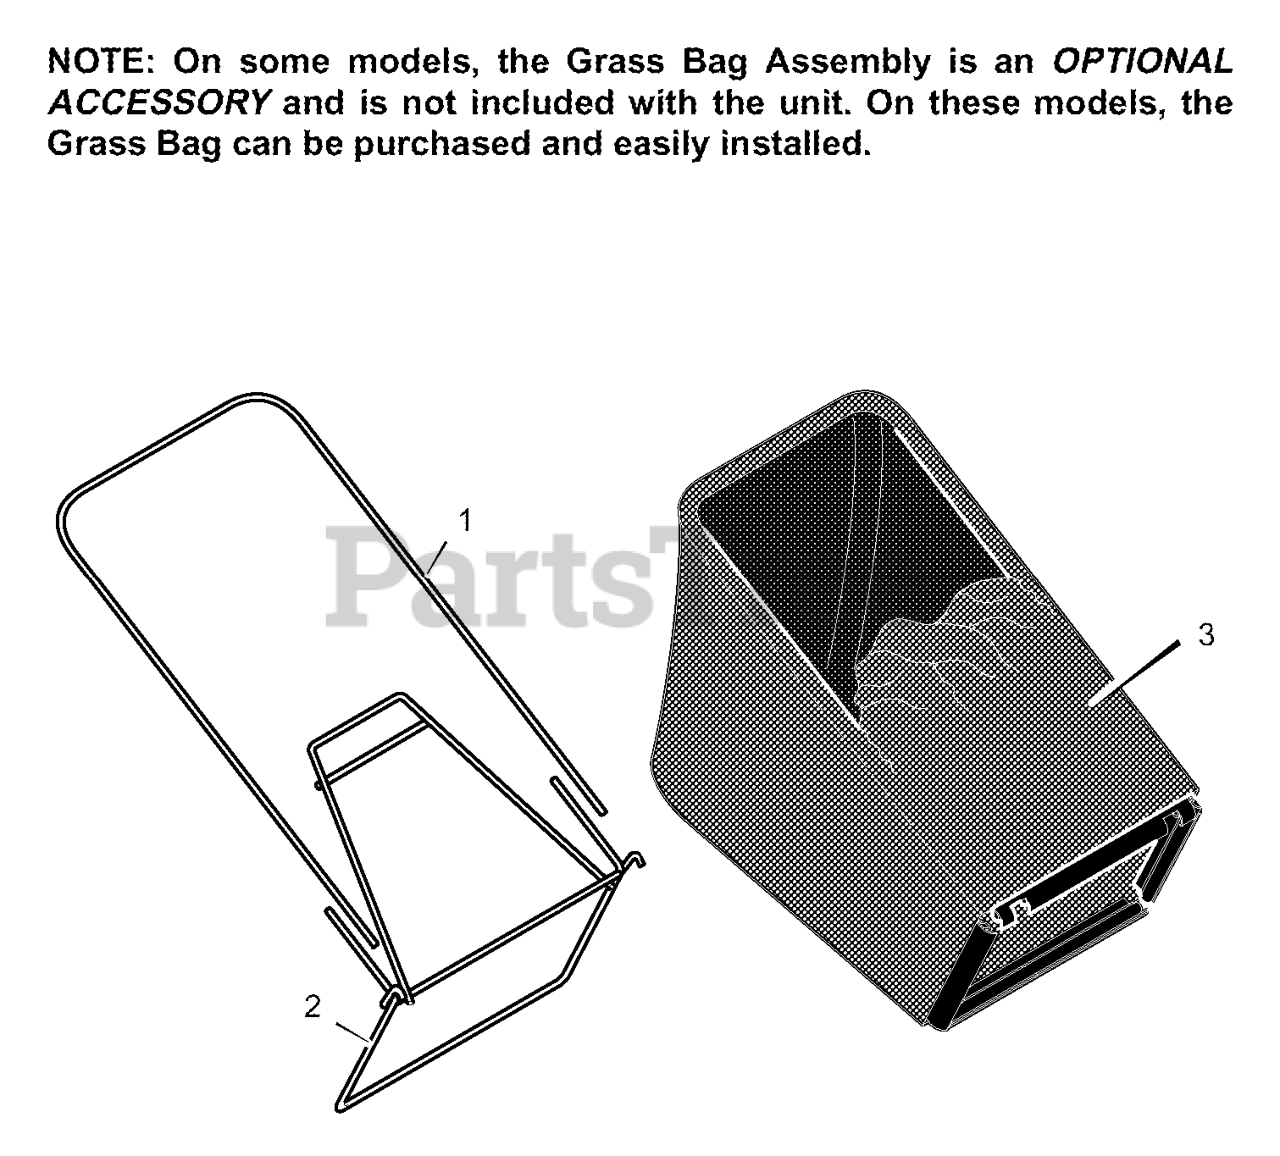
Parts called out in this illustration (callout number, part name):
1	Frame, Top
1-3	Complete Bagger Kit
2	Frame Assembly
3	Bag, Cloth - Black
